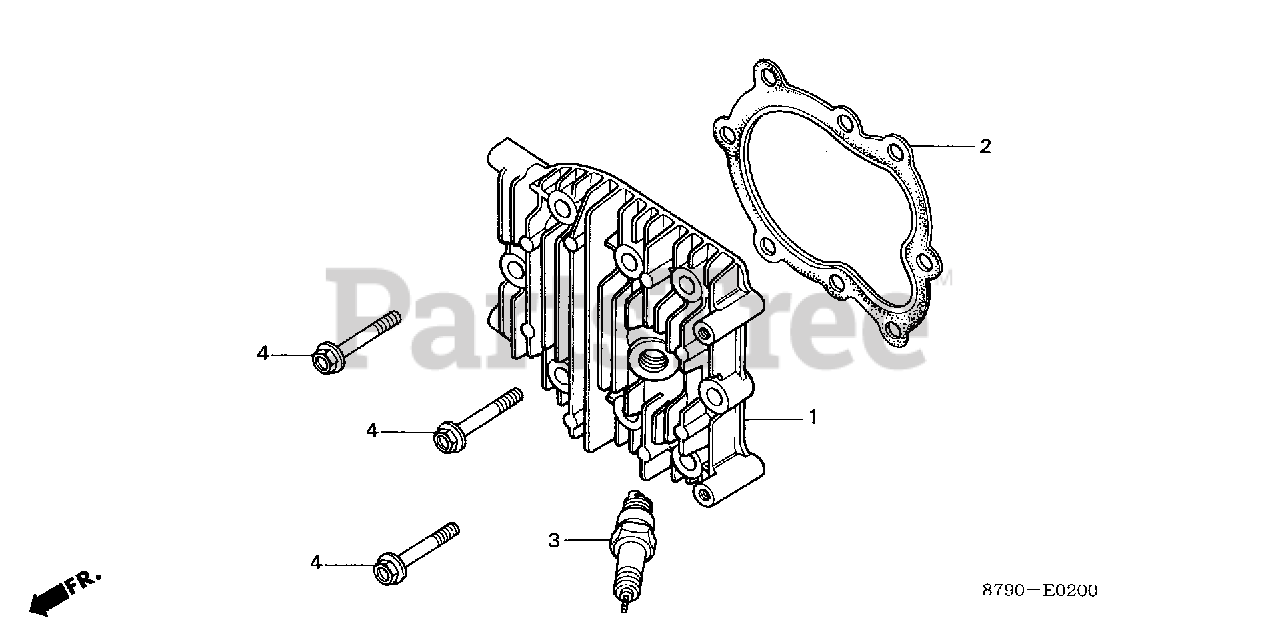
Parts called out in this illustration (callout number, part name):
1	CYLINDER HEAD
2	GASKET, CYLINDER HEAD (NOT AVAILABLE)
3	SPARK PLUG (BR6HS) (NGK)
4	BOLT, FLANGE (8X40)
